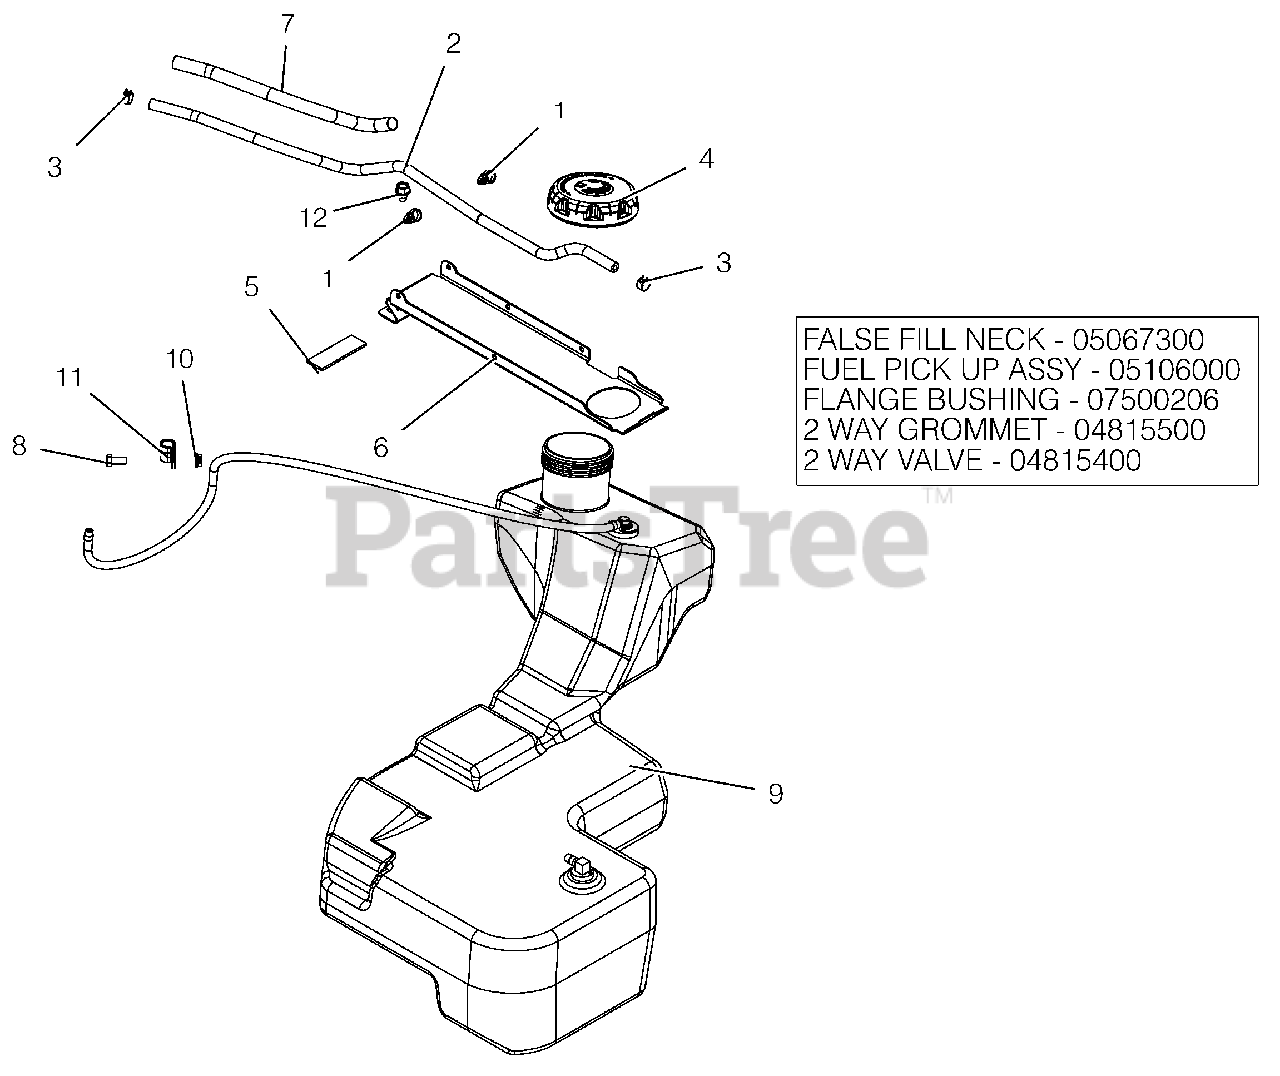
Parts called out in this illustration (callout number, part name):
1	ROUTING CLIP (1/2" ID)
2	HOSE, .25 LOW-PERM BULK GAS
3	CLAMP, FUEL LINE
4	CAP, FUEL VENTIN AUTOLOCK
5	PAD,RBR 1.0"X3.0" W/ADHESIVE
6	BRKT, FUEL TANK HOLD DOWN
7	SLEEVE, THERMAL 12"
8	@BLT-HEX .31-18X.75 GR5 YWZC
9	ASM, HD FUEL TANK
9	INSERT, FUEL NECK FALSE FILL
9	ASM, HD FUEL PICK-UP
9	BSHG-FLG .375X1.062X.625 NITR
9	GROMMET, 2-WAY
9	VALVE, 2-WAY
10	@NUT-LK-CTR-FLG .31-18 YZ GR F
11	CLAMP, CUSHIONED STEEL
12	@SCR-TAP .38-16X.50 HWH TR YWZ
